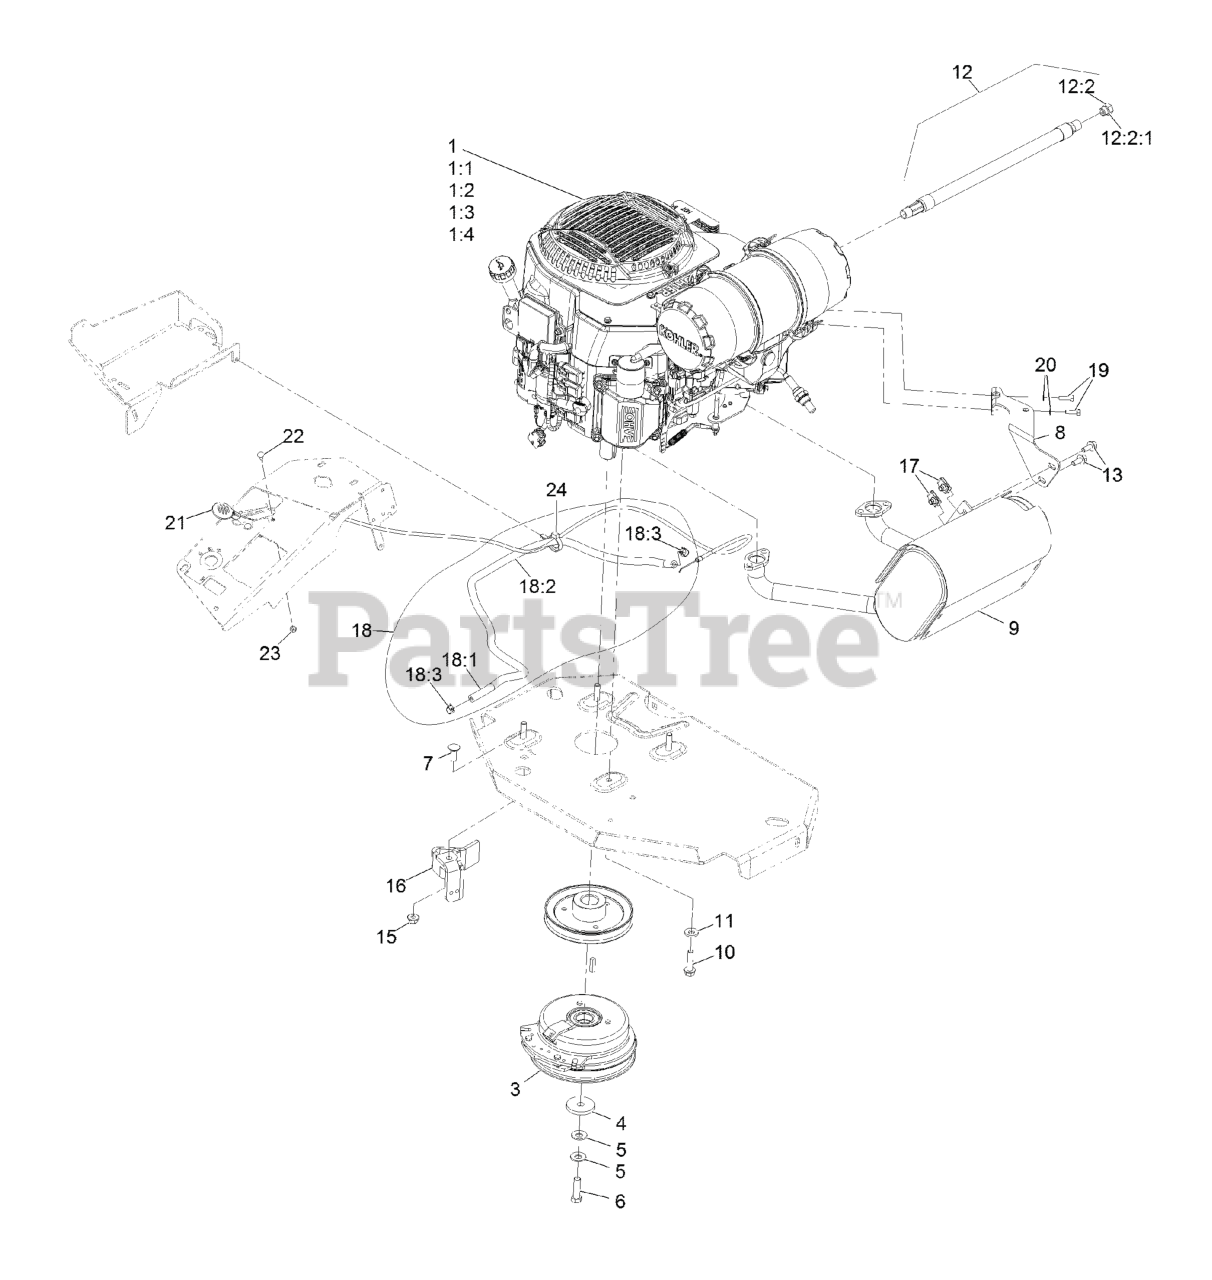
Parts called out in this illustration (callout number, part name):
1:1	Kawasaki 49065-7007 Engine Oil Filter
1:2	Kawasaki 11013-7044 Engine Air Filter
1:3	Kawasaki 11013-7045 Safety Filter
2	WASHER-SPRING
3	WASHER-CLUTCH
4	WASHER-SPRING
6	NUT-HF, NI
7	MUFFLER
9	ENGINE OIL DRAIN HOSE ASM
9:1	PLUG-HH
9:1:1	O-RING
10	CLUTCH KIT
11	BRACKET-MUFFLER
12	CLUTCH-ANCHOR
13	SCREW-HH
14	SCREW-HH
15	SCREW-HH 7/16-20 X 1 1/2 W/LOCTITE
16	SCREW-CARR
18	SCREW-HHF
19	CLAMP-HOSE
20	CLAMP-HOSE
21	HOSE-FUEL
22	WASHER-BELLEVILLE
24	WASHER-PLAIN
27	SCREW-HHF
